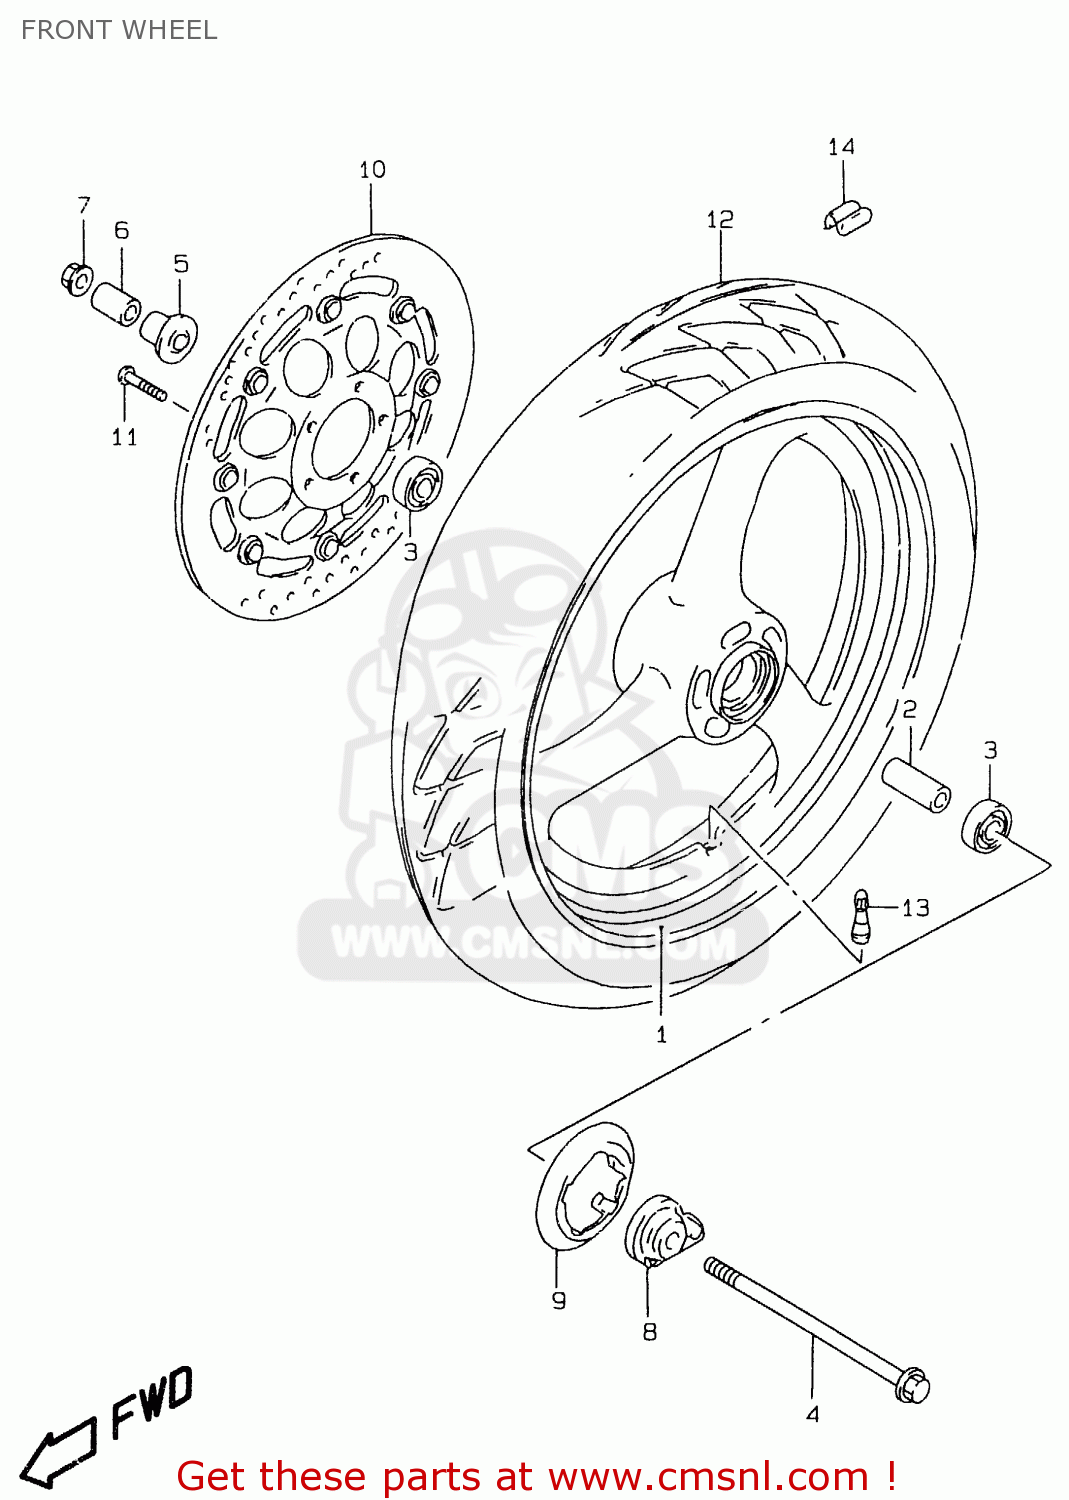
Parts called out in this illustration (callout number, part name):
1	WHEEL,FRONT (MT3.00X17)
2	SPACER(15.3X21.7X63)
3	BEARING
4	AXLE,FR
5	SPACER,FR AXLE
6	SPACER,FR AXLE,R
7	NUT
8	BOX ASSY,SPEEDOMETER GEAR
9	COVER,FRONT HUB,LEFT
10	DISC,FR BRAKE,R
11	BOLT 8X33
12	TIRE,T/L(110/70-17 54H)
13	VALVE ASSY,WHEEL RIM(TR412)
14	BALANCER,WHEEL (10G)
